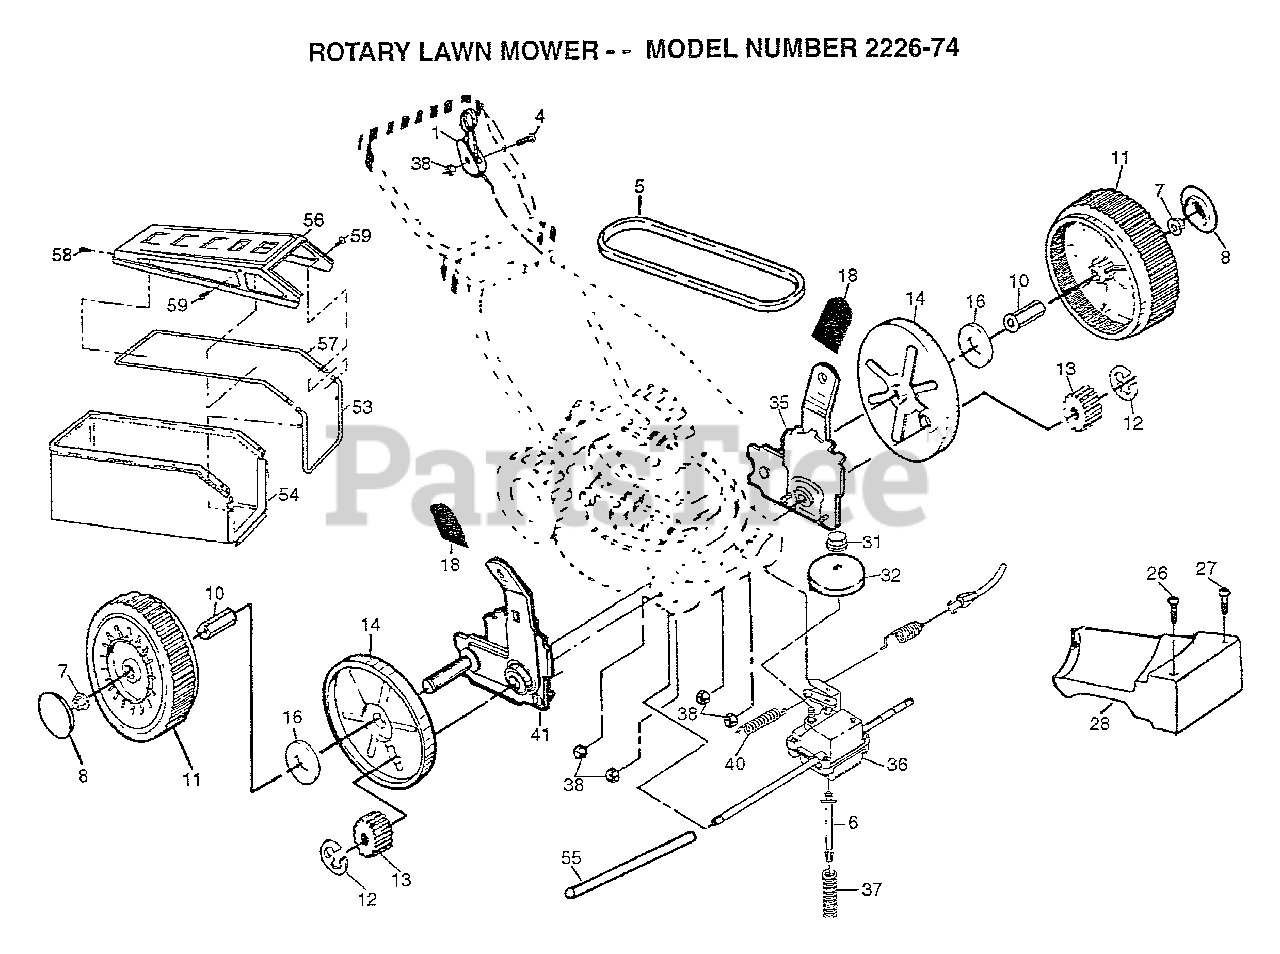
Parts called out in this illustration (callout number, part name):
1	CONTROL.DRV.56.25
4	SCREW.HXHD.WASH.
6	SPRING.RETAINER.
7	NUT.HXFLG.LOCK.
8	HUB CAP
10	BUSHING.HEX
11	WHEEL.DRIVE.ASM
12	E-RING.7/16.RE.
13	PINION.GEAR
14	DUST SHROUD PM
16	WASHER FLUT
18	KNOB PM
26	SCREWL.SLOT.TORXT
27	SCREW.SLOT.TORTX.
28	"COVER.DRIVE 22""RD"
31	LOCKNUT
32	PULLEY.DRIVEN
35	WHEEL.ADJ.ASM.RH.
37	SPRING.TENSION
40	SPRING
41	WHEEL.ADJ.ASM.LH.
53	"FRAME,CATCHER"
54	GRASS CATCHER
55	DRV SHAFT TUBE PM
56	"TOP,CATCHER"
57	"TUBE,CATCHER"
59	SCREW
